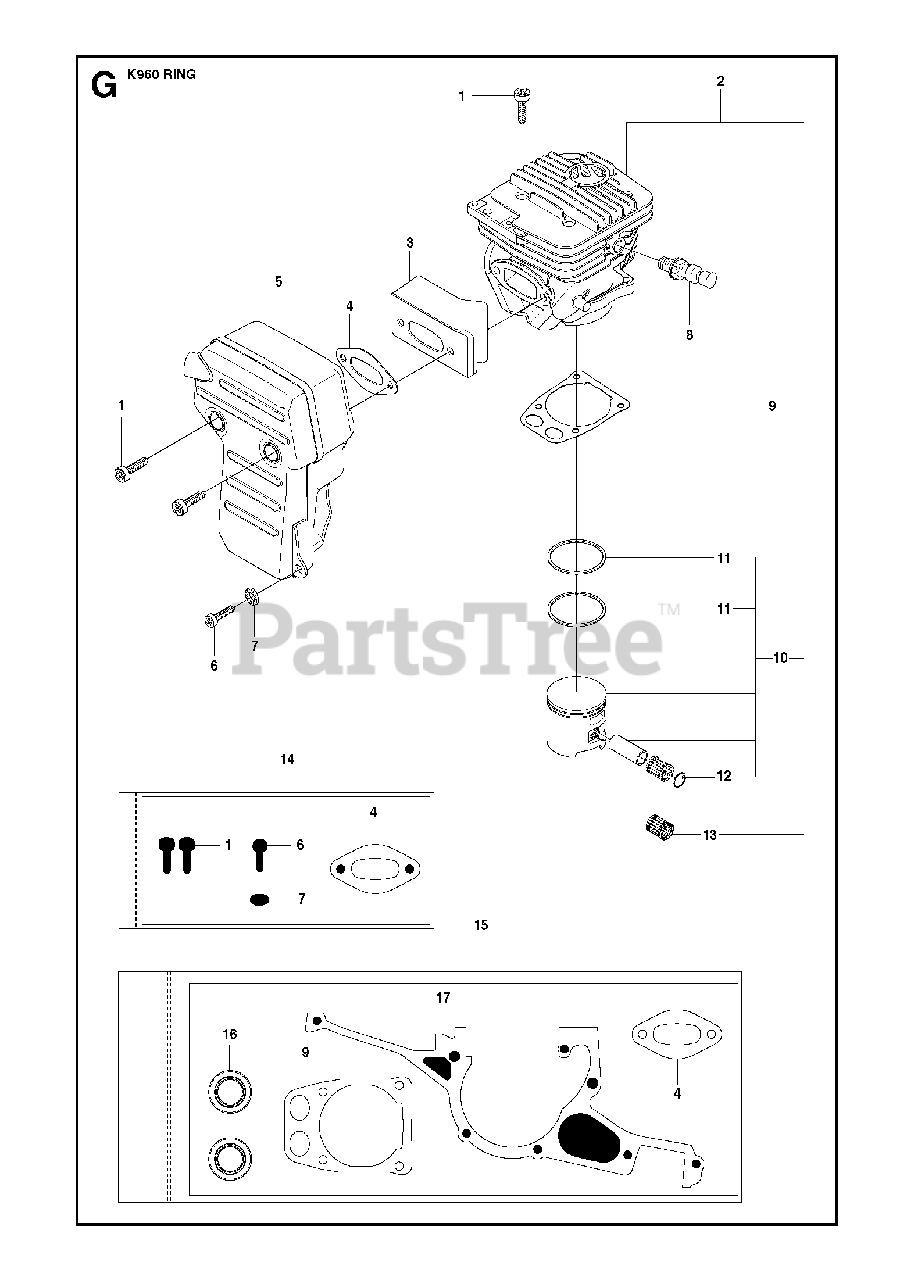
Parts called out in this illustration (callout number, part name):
1	SCREW ITXSCM
2	CYLINDER ASSYIncl. 9, 10, 13
3	HEAT DEFLECTOR
4	GASKET
5	MUFFLER ASSY
6	SCREW ITXSCM
8	DECOMPRESSION VALVE
9	GASKET
10	PISTONIncl. 11, 12
13	NEEDLE BEARING
14	GASKET KITIncl. 1, 4, 6, 7
15	GASKET KITIncl. 4, 9, 16, 17
16	SEALING RING
17	GASKET
